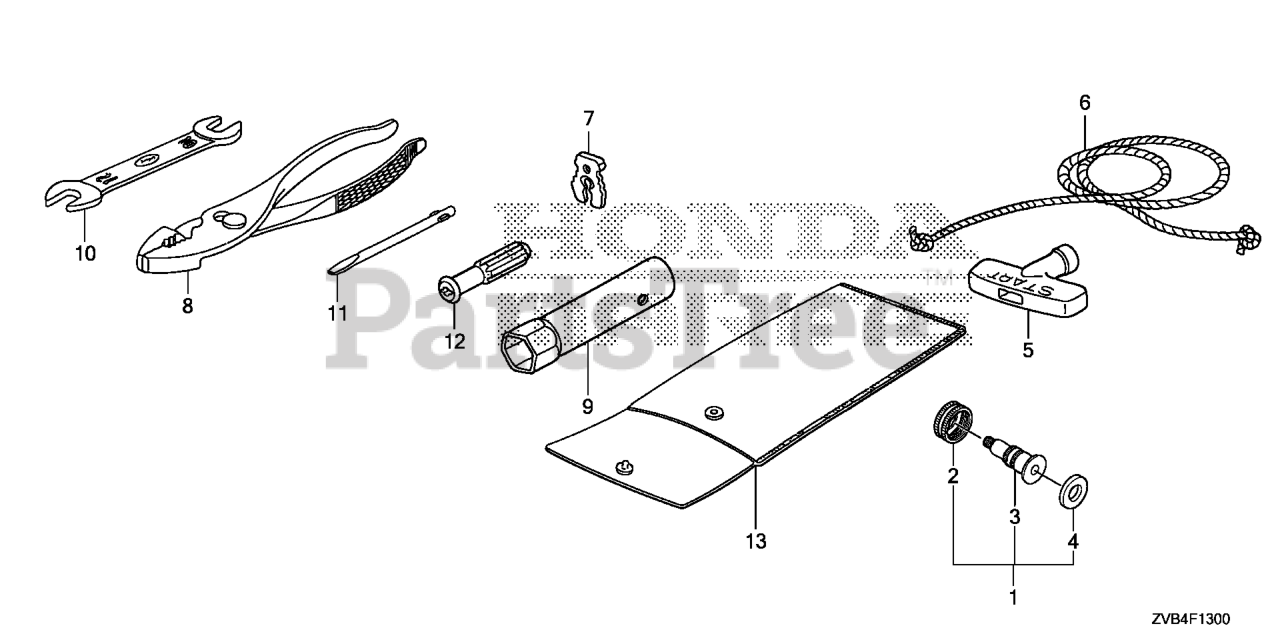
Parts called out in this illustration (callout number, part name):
1	JOINT KIT, WATER HOSE
2	NUT, WATER MOUTH Use from Frame SN 1000929.
3	JOINT, WATER HOSE
4	SEAT, WATER MOUTH Use from Frame SN 1000929.
5	GRIP, STARTER
6	ROPE, RECOIL STARTER (1300MM)
7	CLIP, EMERGENCY LOCK
9	WRENCH, BOX (P16)
10	WRENCH (10X12) (OPEN END)
11	SCREWDRIVER 3, STRAIGHT SLOT (NO. 2)
12	GRIP, SCREW DRIVER
13	BAG, TOOL (160MM)
